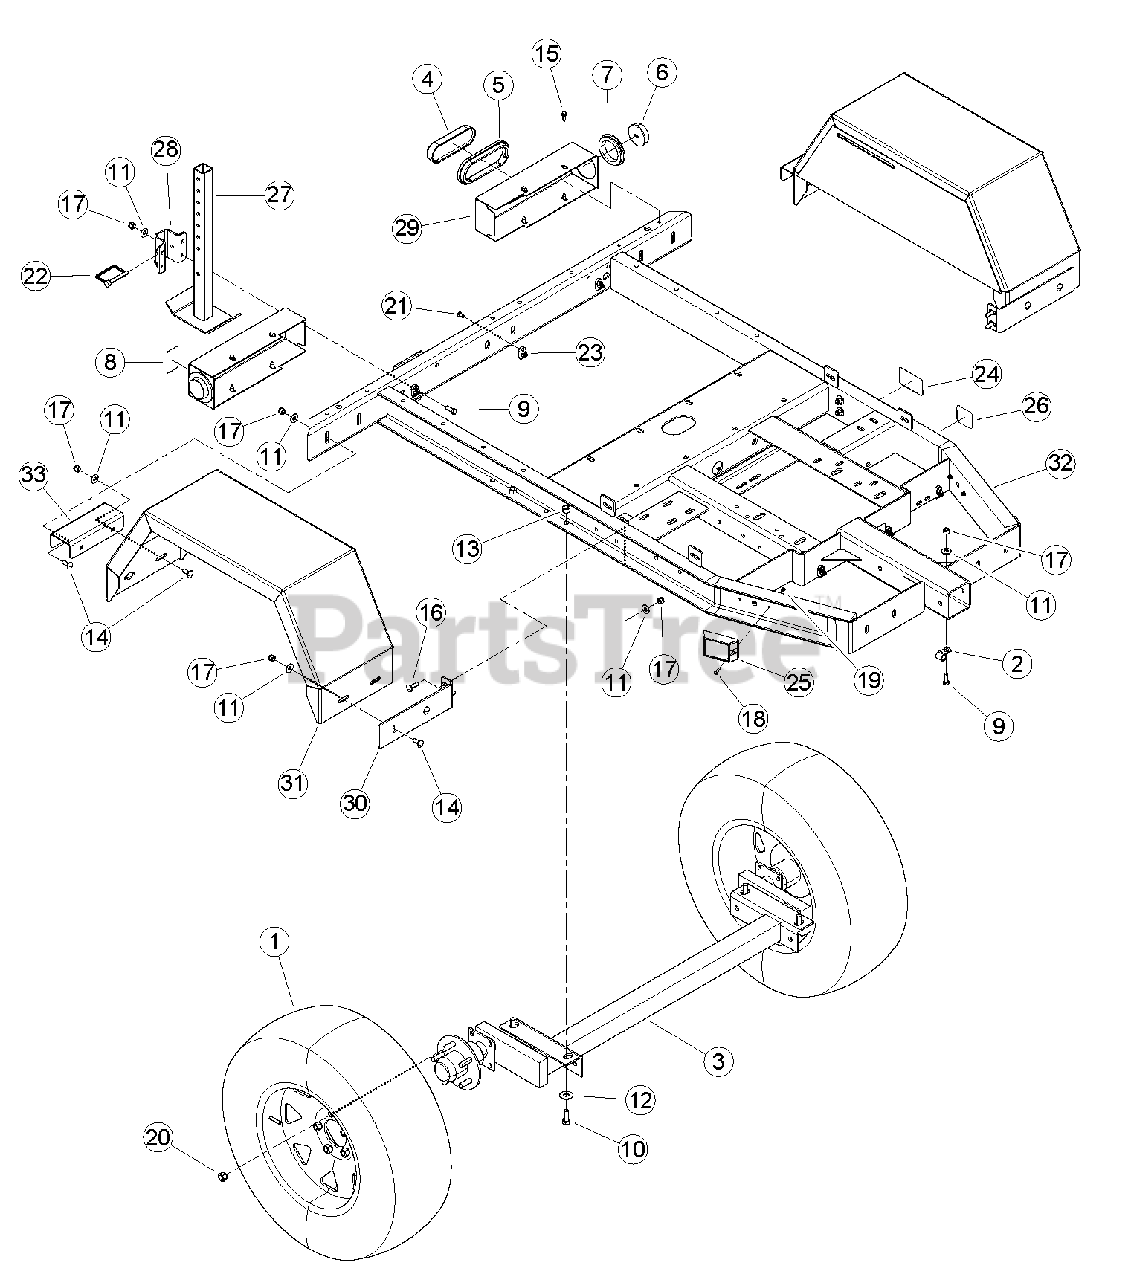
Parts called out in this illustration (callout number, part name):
1	ASSY, 15 INCH TIRE + WHEEL
2	CLAMP, COATED 9/16
3	AXLE, 2500 LB TORSION
4	TAIL LIGHT, OVAL RED
6	LIGHT, RED CLEARANCE
7	GROMMET, CLEARANCE LIGHT
8	REFLECTOR, WIDE ANGLE RED
9	BOLT, 3/8 X 1 HEX HD GR5 ZP
10	BOLT, 1/2 X 1-1/4 HEX HD GR5 NC ZP
11	WASHER, 3/8 FLAT ZP
12	WASHER, 1/2 FLAT ZP
13	NUT, 1/2 CENTERLOCK GRB ZP
14	BOLT, 3/8 X 1 CRG GR5 NC ZP
15	SCREW, 11/32 X 7/8 HWH AB THREAD ZP
16	BOLT, 3/8 X 1-1/4 CRG GR5 NC ZP
17	NUT, 3/8 NE NYLOCK ZP
18	MACH. SCREW,10-24 X 1 RND HD PHL ZP
19	NUT, 10/24 NYLOCK TYPE NM ZP
20	NUT, 1/2-20 WHEEL
21	RIVET, AL BLIND 1/4 X 3/4 DOME HEAD
22	PIN, 3/8" X 2-3/4" SNAP
23	CLAMP, CABLE MOUNT
25	LIGHT, AMBER SIDE MARKER
26	DECAL, EPA EMISSION
27	WELDMENT, REAR STABILIZER
28	GUIDE, TRAILER SUPPORT
29	BRACKET, TAILLIGHT
30	BRACKET, FENDER
31	WELDMENT, CHIPPER FENDER
32	WELDMENT, CHIPPER TRAILER
33	PLATE, FENDER SPACER
